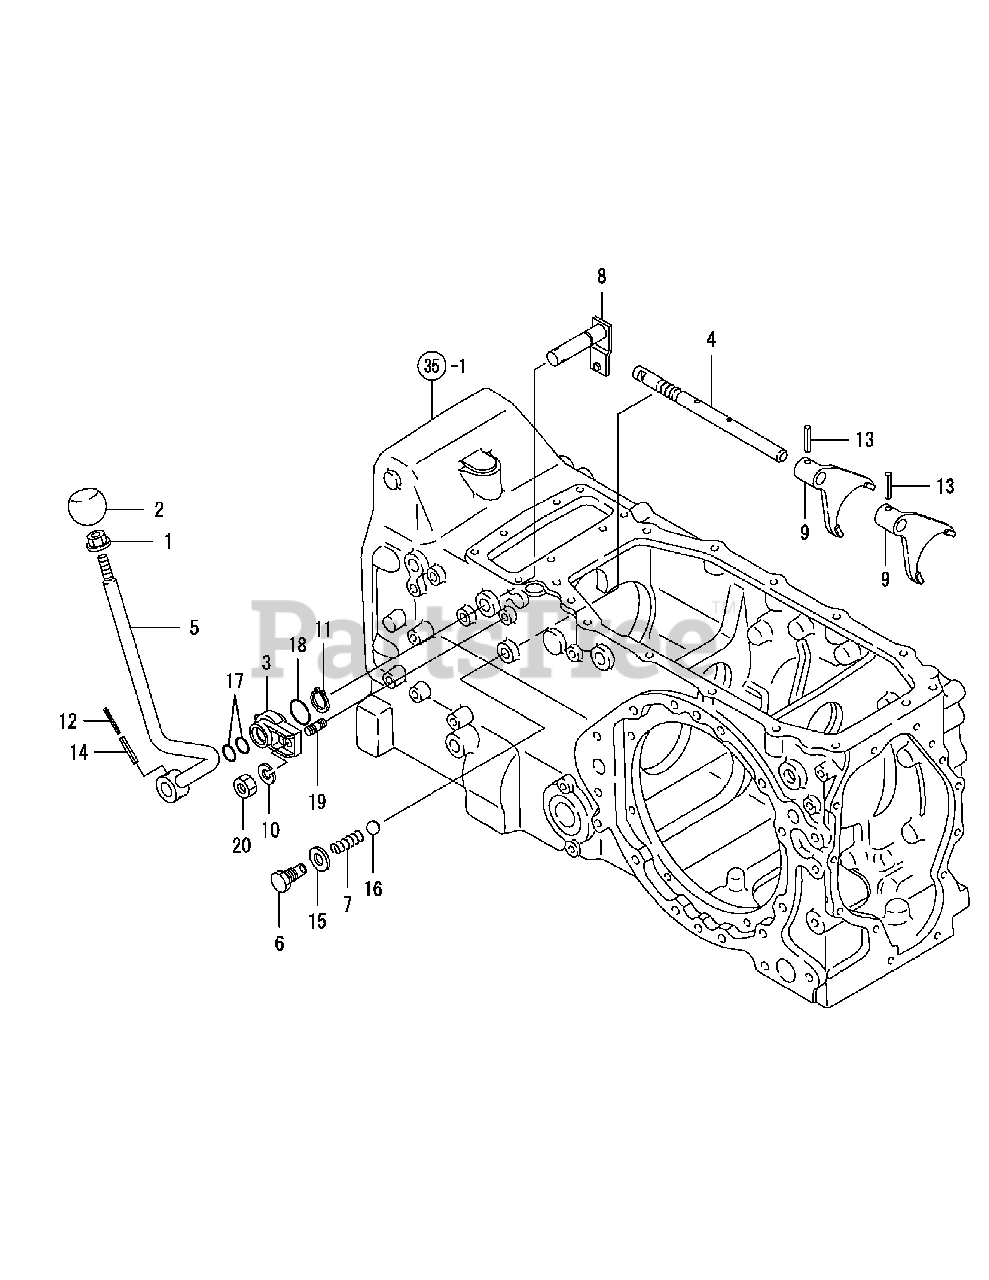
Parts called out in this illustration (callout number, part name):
1	NUT W/WASHER 10
5	LEVER, RANGE SHIFT
7	SPRING, FORK LOCK
12	SPRING PIN 3.5X32
13	SPRING PIN 6X32
14	SPRING PIN 6X32
16	BALL 1/4, STEEL
17	O-RING 1A P-16.0
18	O-RING 1A G-25.0
